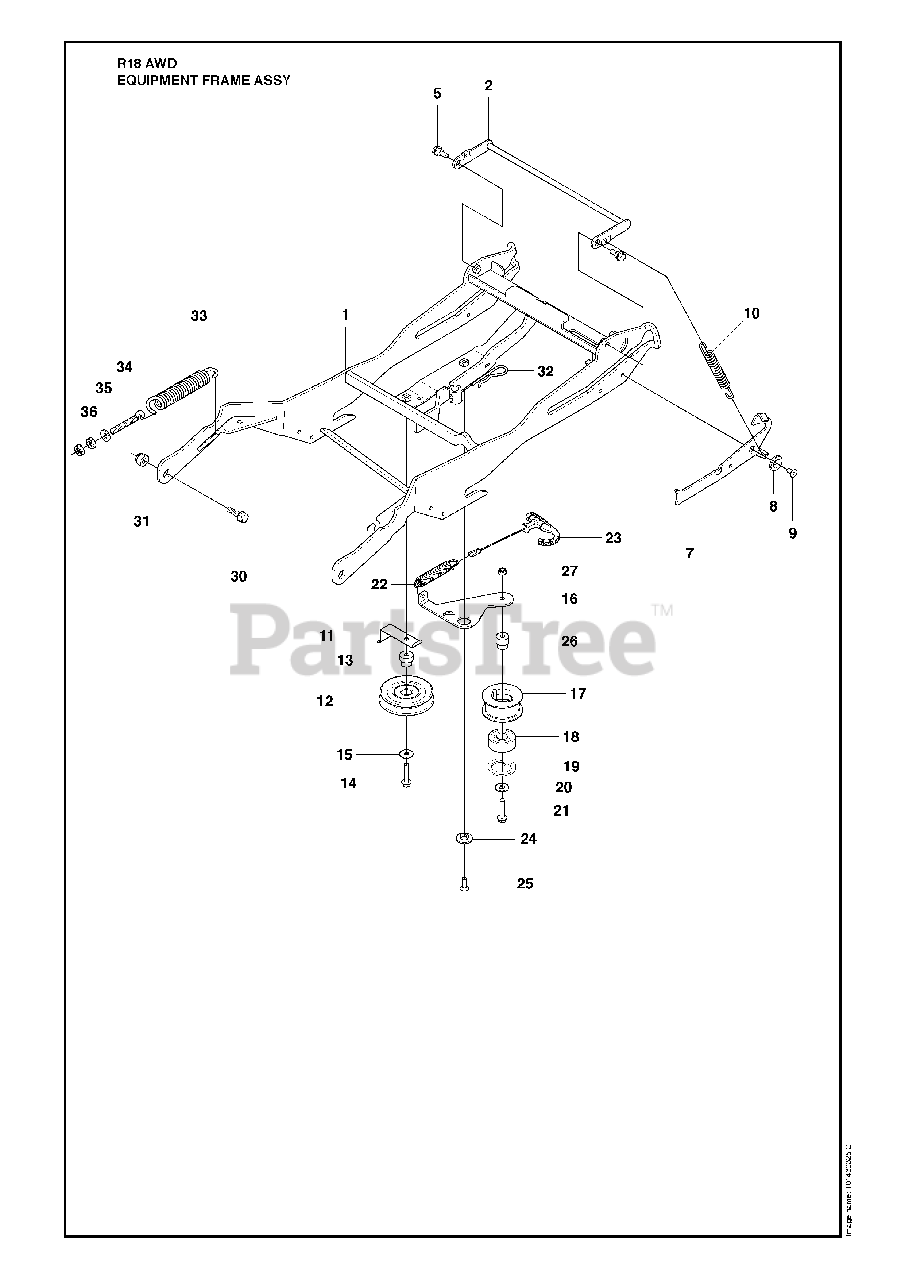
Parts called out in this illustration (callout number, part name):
8	SPACER
9	SCREW IHCSFM
11	BELT GUIDE
17	%PULLEY
18	BALL BEARING 6004-2RS1
19	RETAINING RING
23	HANDLE ASSY
24	WASHER
27	LOCKNUT M8
31	Lock Nut, Fiber M12 DIN 985 Z/P
35	WASHER
36	NUT
